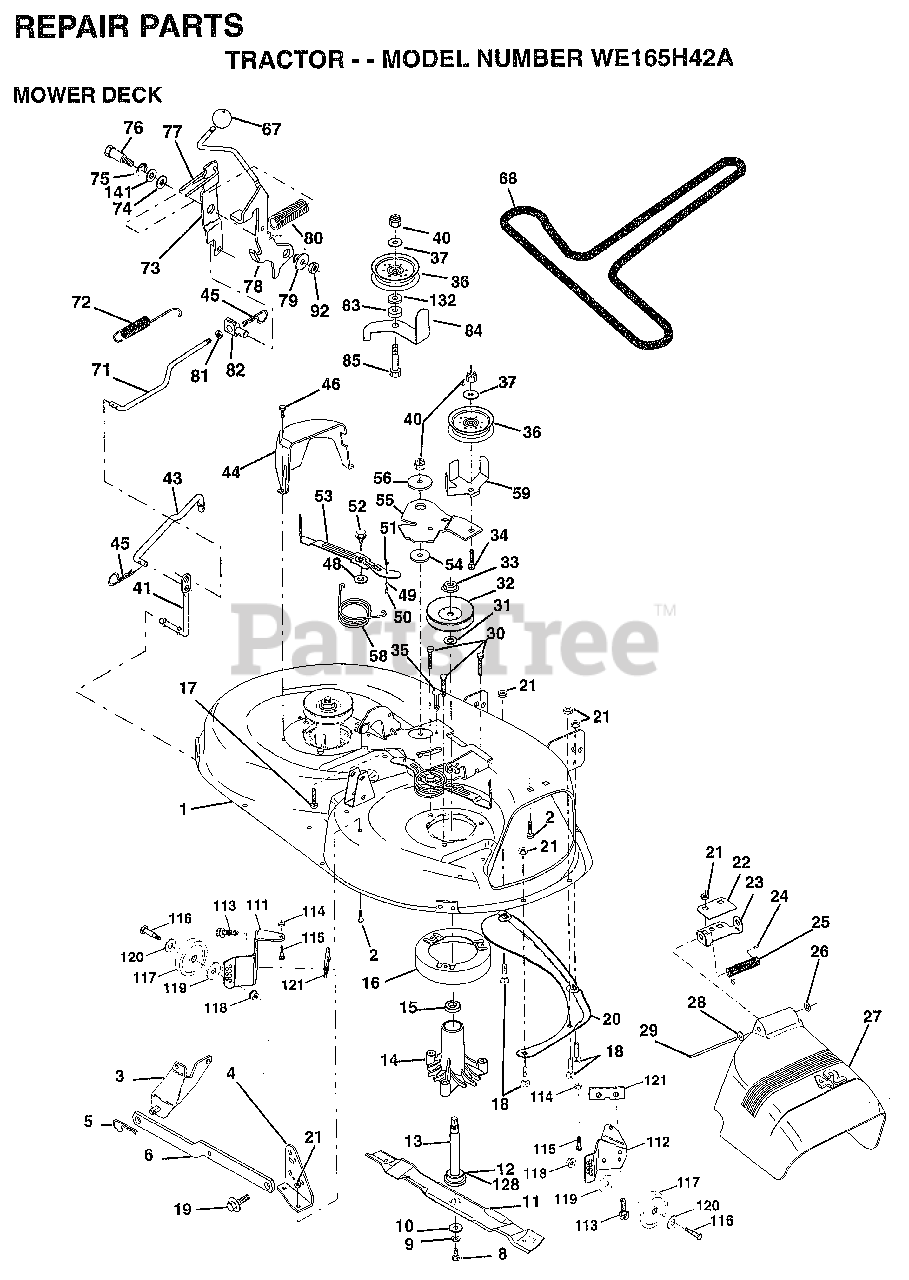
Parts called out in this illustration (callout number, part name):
1	DECK.WELD.42.
2	BOLT
3	BRKT ASM SWAY BAR
4	BRKT DECK SW BAR
8	BLADE BOLT
10	WASHER.HARD.BLADE
11	"BLADE.42"" HIPERF"
12	BEARING.BALL
14	HSG ASM MANDREL
15	BEARING
16	STRIPPER RND MWR
17	BOLT RDHD 3/8-16
18	BOLT
19	BOLT SHD 5/16-18
20	BAFFLE VORTEX 42
22	STIFFENER BRKT
23	DEFLECTOR BRKT
25	SPRING TORSION
27	DEFLECTOR.SHIELD
28	WASHER
29	HINGE ROD
30	"SCREW-THD ROLL,WA"
31	WASHER
32	PULLEY.MANDREL.42
34	BOLT
35	XMAS TREE FASTNER
36	FLAT IDLER PULLEY
37	WASHER
41	PIVOT ROD
43	ROD CLUTCH W/NIBS
44	GUARD MAND LH BLK
46	SCREW.1/4-20X5/8
48	HARD SMALL WASHER
49	ROLLER ASM-CAM
50	SHOULDER BOLT
51	LOCKNUT
52	BOLT.SHLD.5/16-18
53	BRAKE PAD ARM ASM
54	HARDENED WASHER
55	ARM-IDLER
56	SPACER RETAINER
58	SPRING TORSN BRAK
59	GUARD IDLER TUV
67	KNOB.RD.7/16-14
68	BELT.V.T-PATH
71	ROD CLUTCH 38/42
72	RETURN SPRING
73	CLUTCH ARM SECOND
74	WASHER
75	RING
76	SHOULDER BOLT
77	SPRING KEEPER
78	LEVER.ASM.CLUTCH
79	BUSHING
80	SPRING.CLUTCH.MWR
81	NUT
82	TRUNION ADJ
83	WASHER
84	"KEEPER-BELT,FIXED"
85	BOLT RDHD 3/8-16
92	NUT
111	BRACKET.GWHL.LH.
112	BRACKET.GWHL.RH.
113	SCREW
116	BOLT M
117	WHEEL.GAGE.BLK.PL
118	LOCKNUT
119	WASHER
120	WASHER
121	BRACKET.EXTRD.GWL
128	WASHER.FELT.
132	WASHER GT
141	WASHER .T
